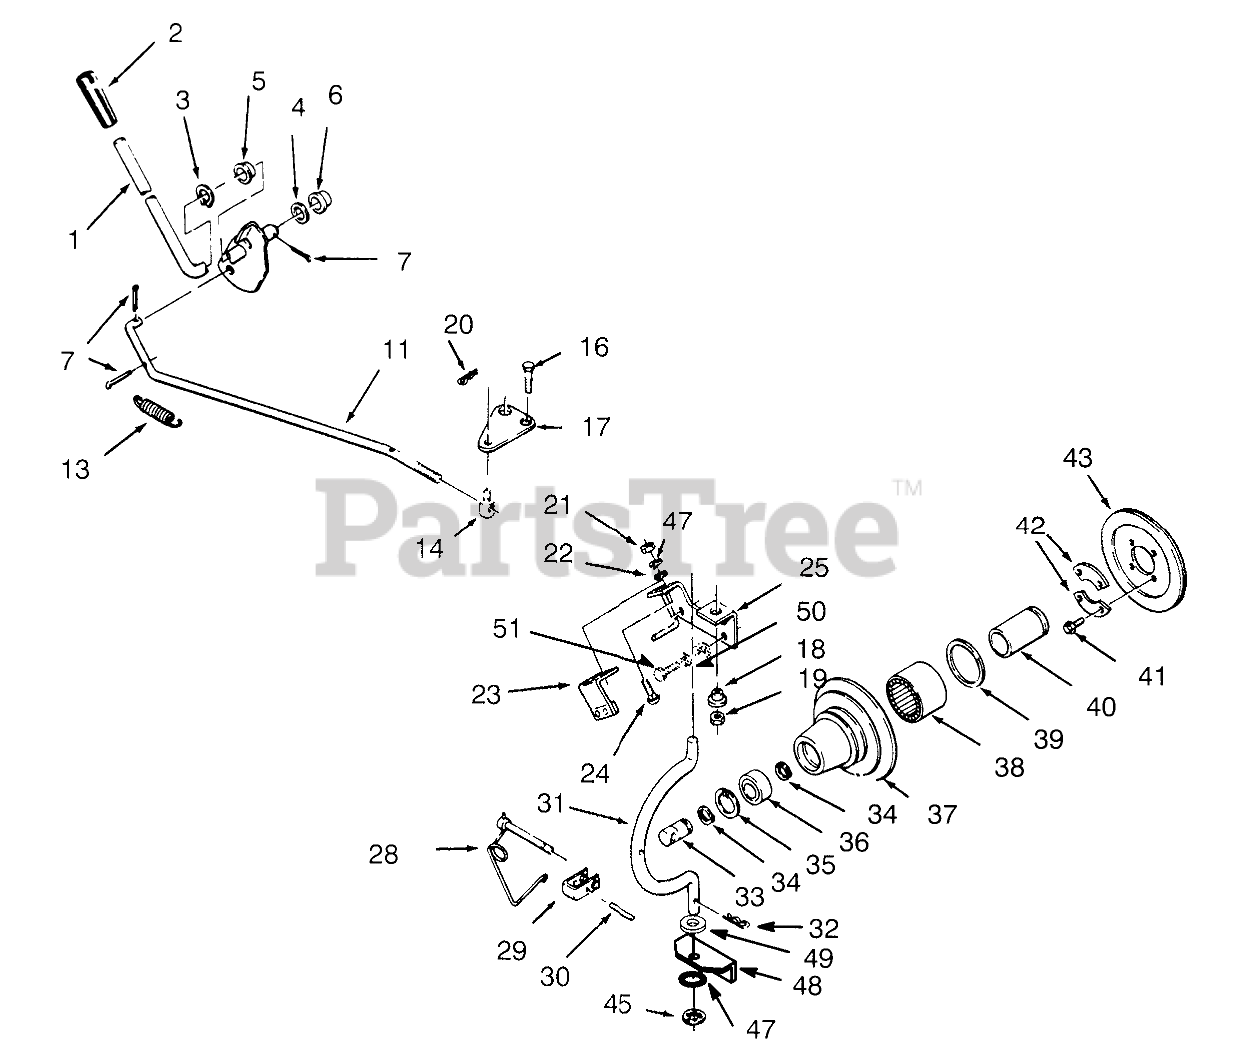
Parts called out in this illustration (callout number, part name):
1	ASSY PTO CLUTCH LEVE
2	GRIP
3	RING-EXT GRIP
4	SHIM-WASHER
5	BUSHING-NYLINER
6	NYLINER BUSHING
7	PIN-COTTER
11	ROD-PTO CLUTCH
13	SPRING
14	TRUNNION
16	SCREW-HH
17	PLATE
18	SPACER-LIFT LINK
19	NUT-LOCK, NI
20	Hairpin Cotter
21	NUT-JAM
22	WASHER-FLAT
23	ASM-Bracket
24	SCREW-CARR
25	Bracket-Engine
28	LOCKING PIN ASM
29	CLEVIS
31	ROD-HOUSING
32	Hairpin
33	SHAFT-PTO
34	Ring-Snap
35	RING-RETAINING
36	BEARING-BALL
37	Housing-Clutch
38	Seal
39	SEAL-OIL
40	RACE-BEARING
41	SCREW-HEX HD CAP
42	RETAINER
43	Facing-Clutch
45	RING-REINFORCED CIRC
47	WASHER-LOCK
48	Axle
49	WASHER-FLAT
50	WASHER-LOCK
51	SCREW-HH
